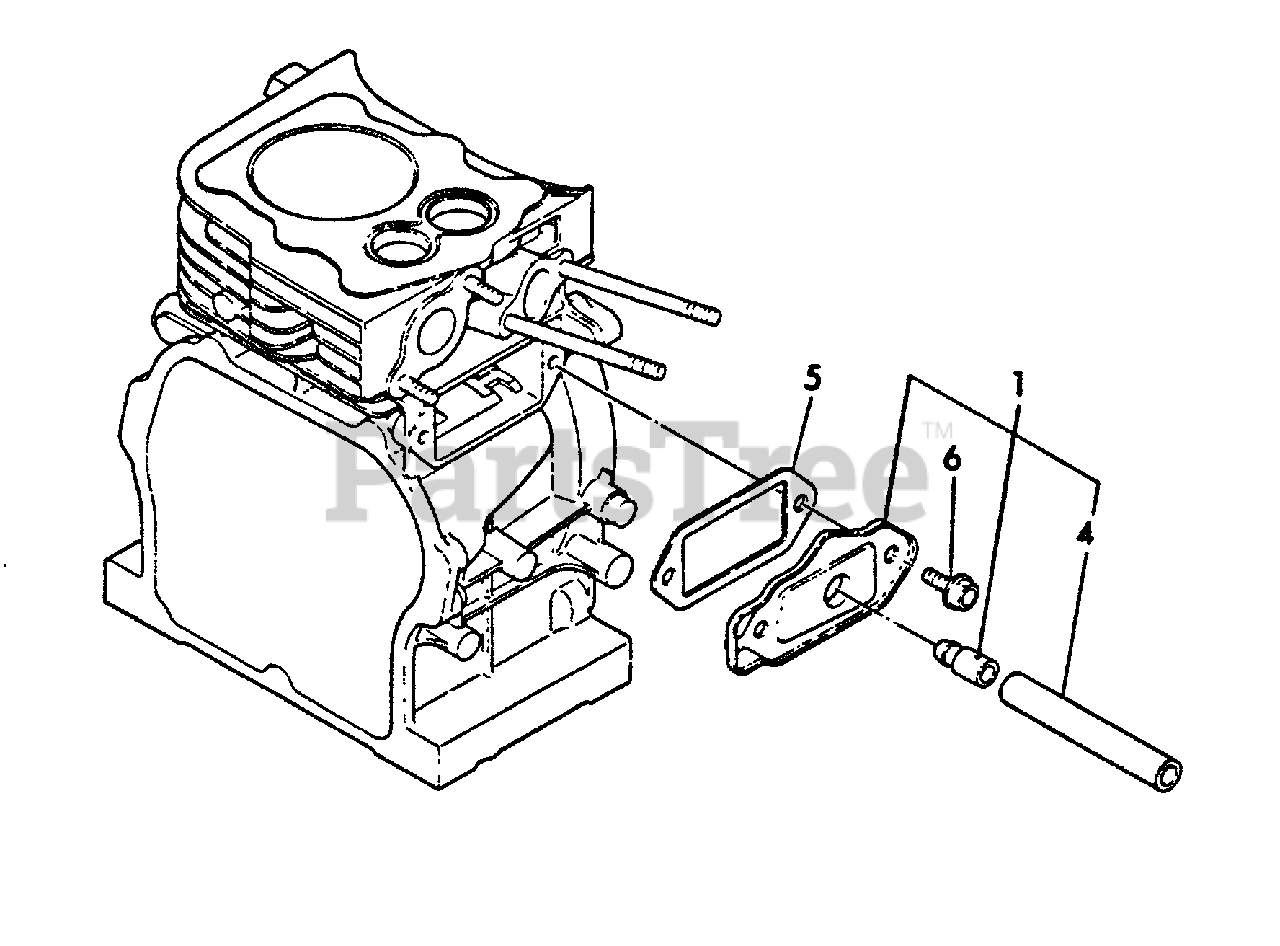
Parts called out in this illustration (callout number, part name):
1	VENT, FUEL TANK
4	PIPE - BREATHER
5	GASKET
6	BOLT - 6X8 -- PLATED
